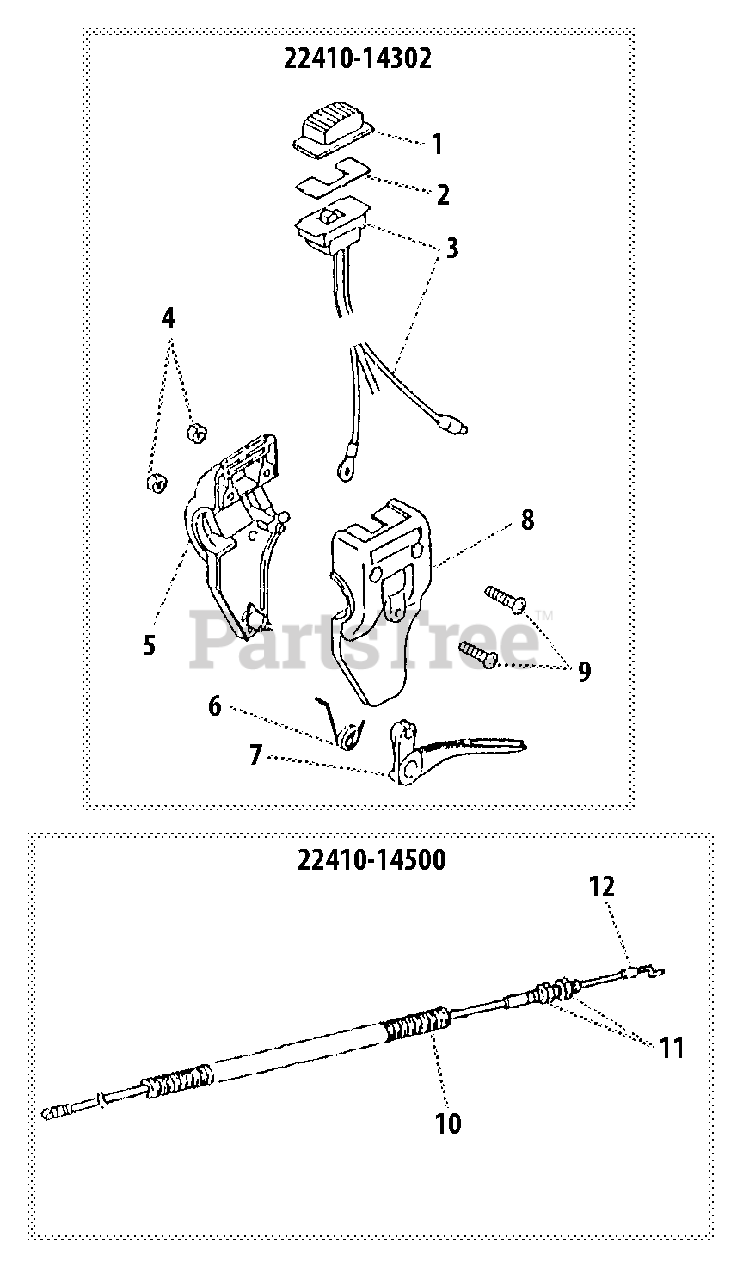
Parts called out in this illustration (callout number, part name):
1	KNOB
2	PLATE, SWITCH
3	SWITCH
4	NUT - 5
5	BRACKET - RIGHT
6	SPRING, TRIGGER
7	TRIGGER, THROTTLE
8	BRACKET - LEFT
9	SCREW - 5X20
10	TUBE
11	NUT - 6
12	CABLE, THROTTLE
22410-14302	THROTTLE CONTROL KIT
22410-14500	THROTTLE CABLE ASSY
